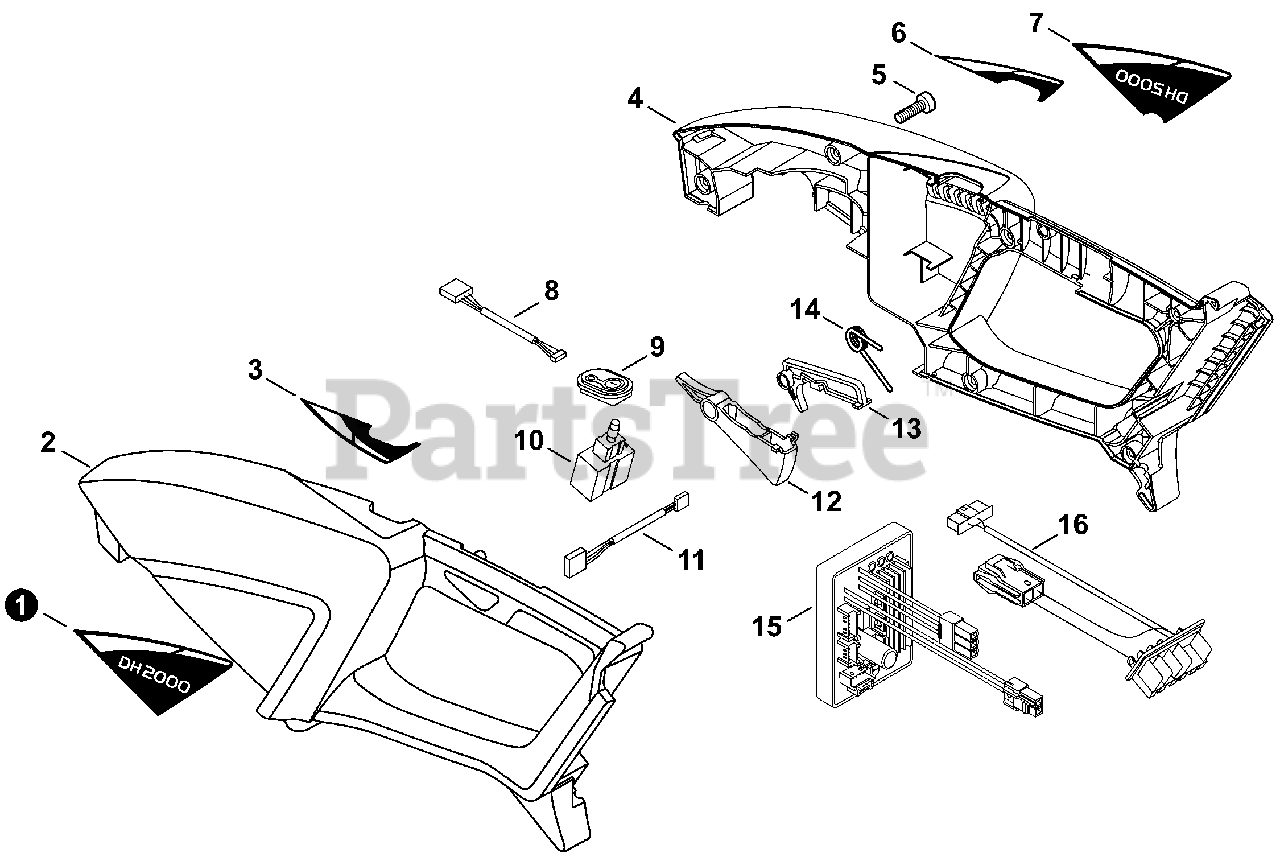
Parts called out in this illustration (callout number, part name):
1	LABEL - MODEL DH2000, LEFT
2	BODY, HANDLE - LEFT
3	LABEL, ON-OFF, LEFT
4	BODY, HANDLE - RIGHT
5	BOLT, TORX 4×16
6	LABEL, ON-OFF, RIGHT
7	LABEL - MODEL DH2000, RIGHT
8	LEAD, ON-OFF
9	SWITCH, ON-OFF
11	WIRE HARNESS
12	TRIGGER
13	LOCKOUT, TRIGGER
14	SPRING, TORSION
15	CONTROL BOARD ASSY
16	TERMINAL, LEAD
